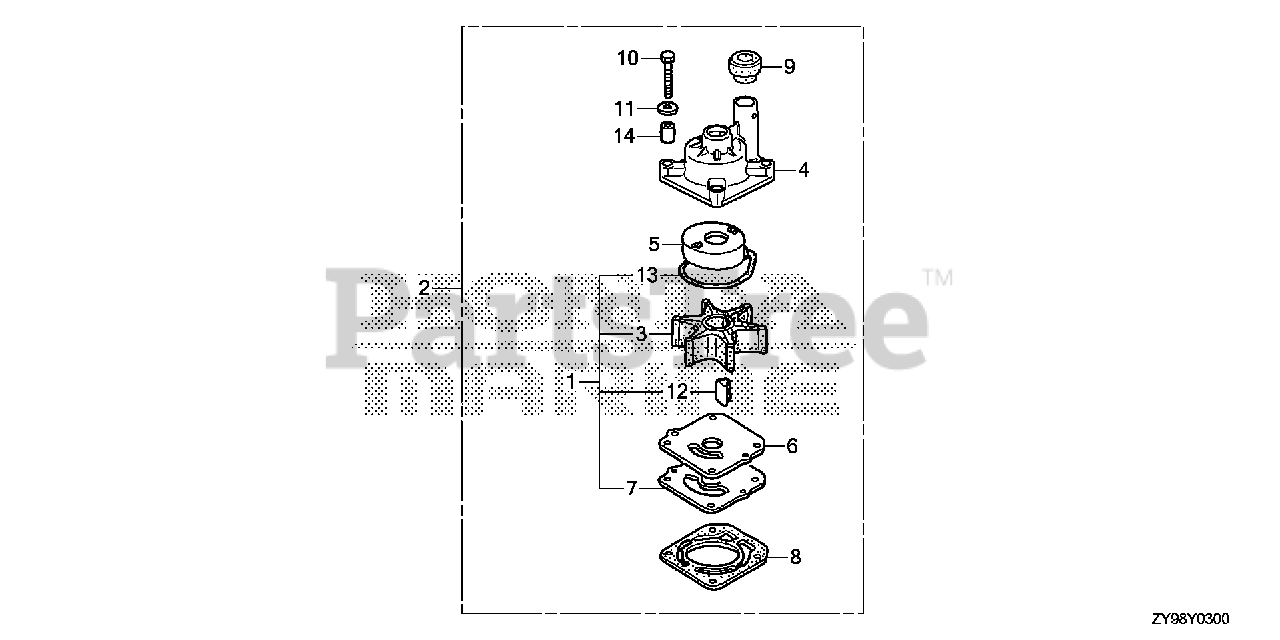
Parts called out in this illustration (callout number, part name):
1	PUMP KIT, IMPELLER
2	PUMP KIT, IMPELLER
3	IMPELLER, PUMP
4	HOUSING, IMPELLER
5	LINER, PUMP
6	COVER, IMPELLER
7	GASKET B, IMPELLER
8	GASKET, WATER PUMP
9	RING, WATER TUBE SEAL
10	BOLT, HEX. (8X55)
11	WASHER (8MM)
12	KEY, WOODRUFF
13	O-RING, WATER PUMP
14	COLLAR, DISTANCE
